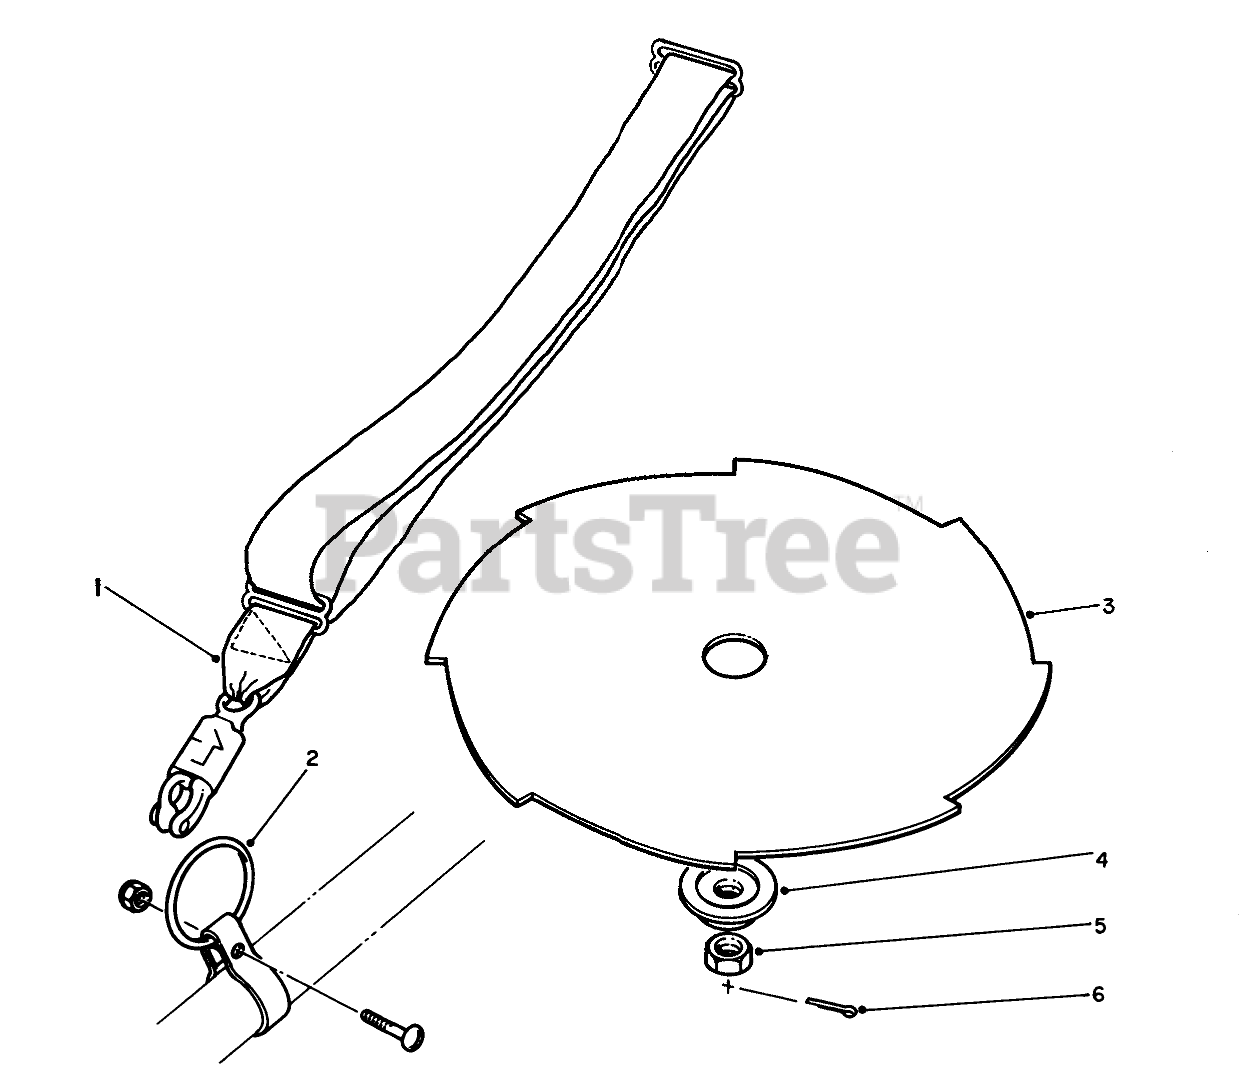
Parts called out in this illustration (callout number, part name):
1	Shoulder Strap
2	HARNESS CLAMP/RING KIT
3	8" Blade (8T)
4	Blade Adapter
5	Nut-Special, L.H. Metric
6	1/16 X 1 LG COTTER PIN
